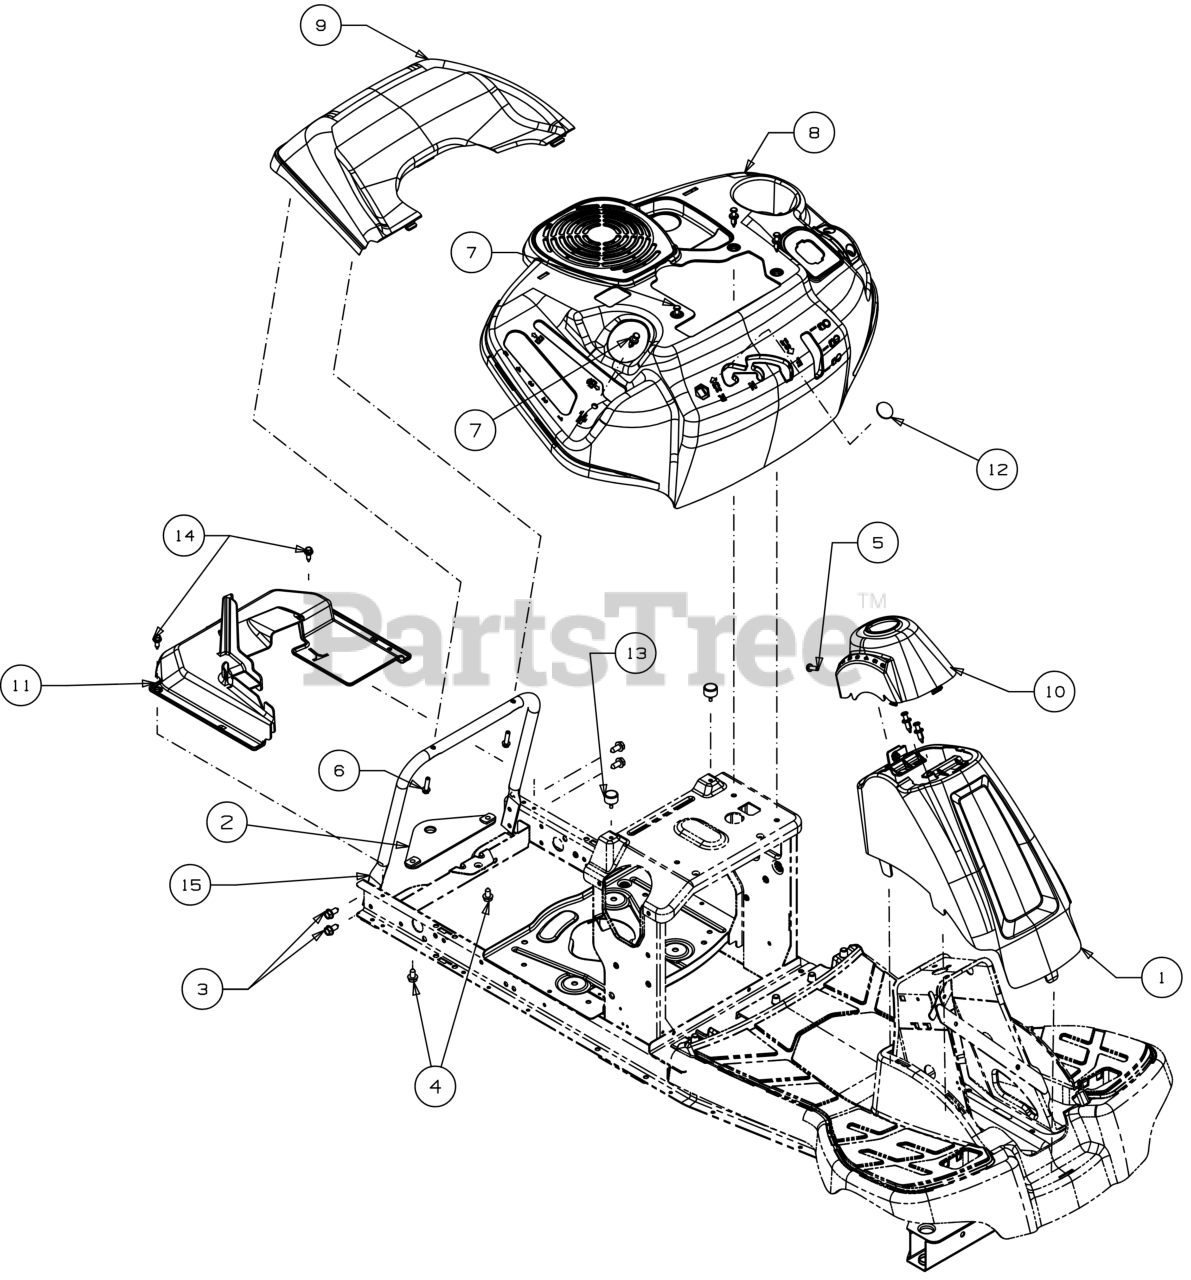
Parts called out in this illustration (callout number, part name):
1	COLUMN COVER ASSEMBLY (MTD RED)
3	SCREW 5/16-18 x .750
4	SCREW 5/16-18 x .625
5	SCREW 1/4-20X.75
6	SCREW 1/4-15 x 1.00
7	PLASTIC RIVET
8	FENDER ASSEMBLY
9	REAR COVER
10	COLUMN STEERING CAP
11	DRIVE OVER REAR
12	CHOKE PLUG
13	BUMPER .62 DIA x .50
14	SHOULDER SCREW
